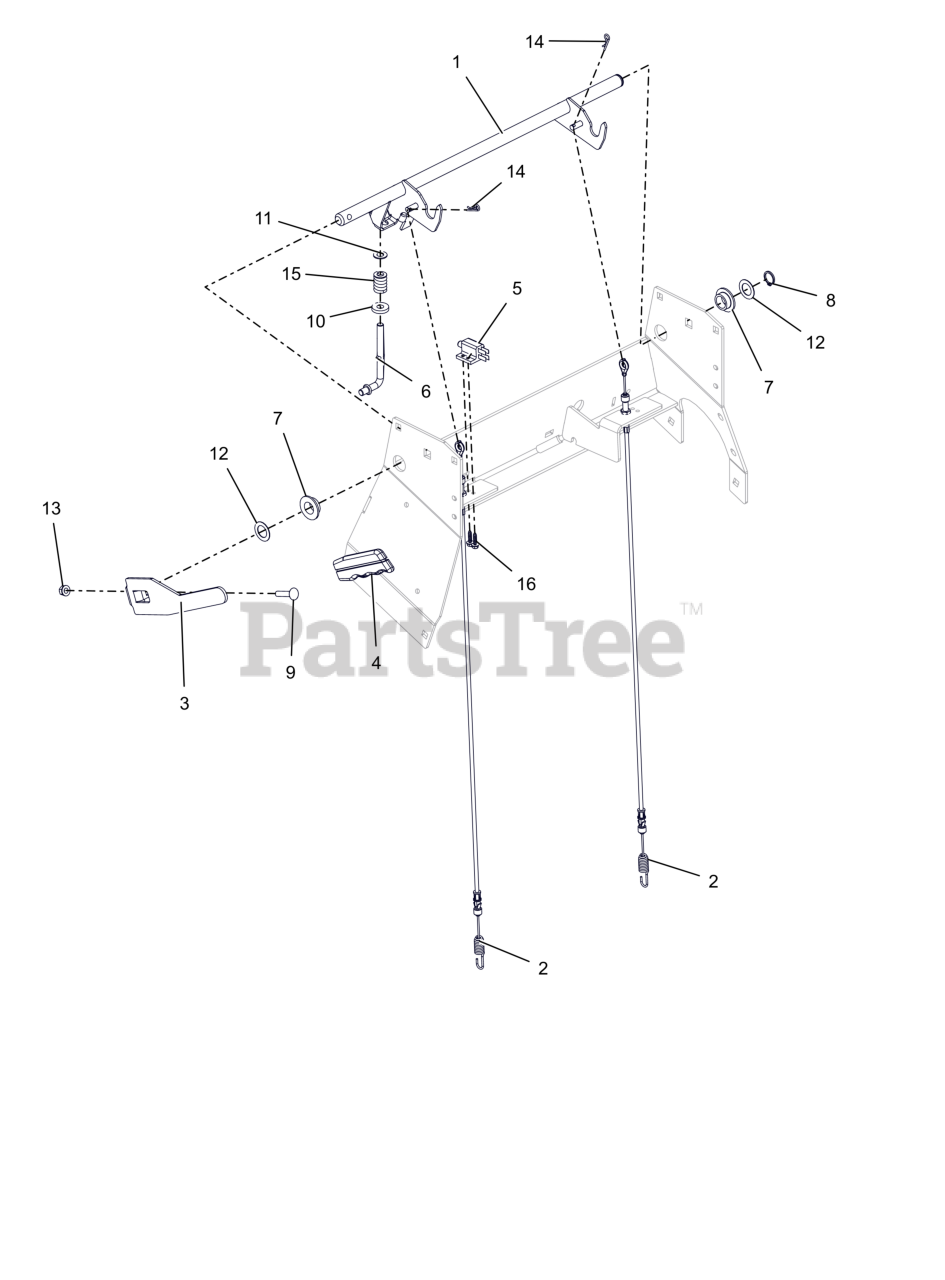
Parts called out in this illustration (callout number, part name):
1	WLDMT, PARKING BRAKE SHAFT (BLACK)
2	CABLE, BREAK - PROSTANCE
3	HANDLE, PARK BRAKE (BLACK)
4	GRIP, PARKING BRAKE (YELLOW)
5	SWITCH- DOUBLE POLE N.O./N.O.
6	LINK, OVER CENTER BRAKE
7	BSHG-FLG .762X1.48X.44 NYL
8	RG-RTNG-EXT .689X.078
9	BLT,RHSN .31-18X1.50 G5 ZCC
10	WSHR, FLT .406X1.00X.188 ZCC
11	WSHR-FL-STL 0.406X0.812X0.055 HRD
12	WSHR-FL-STL 0.76X1.225X0.032 ZCC
13	NUT,LK-CTR-FLG .31-18 GF ZCC
14	PIN, HAIR #213 .08X1.19 ZCC
15	SG-COMP .187X.56X1.62
16	SCR, PLASTITE-HWH 0.2 X 0.75 ZC120
